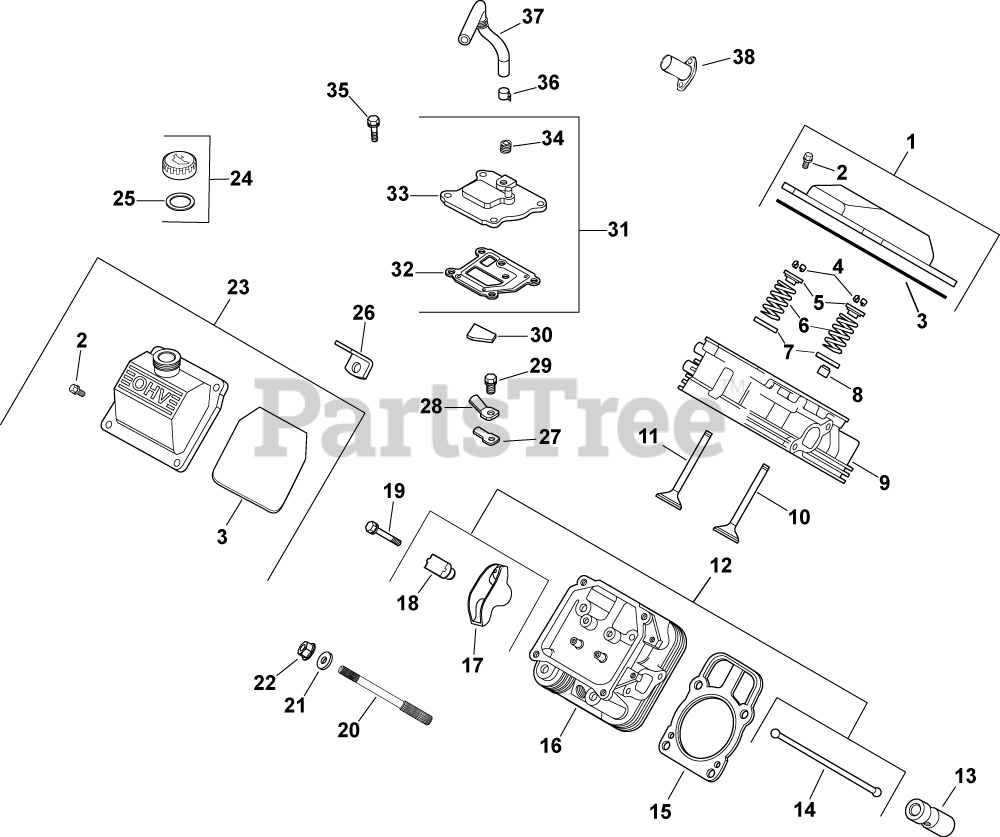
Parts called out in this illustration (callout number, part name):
1	KIT, VALVE COVER-PLAIN
2	SCREW, SHOULDER
4	KIT, RETAINER
5	RETAINER, VALVE SPRING - USE 25 173 28-S
6	SPRING, VALVE
7	RETAINER, SPRING
8	SEAL, VALVE STEM - (#2503214S)
9	HEAD, SERVICE ASSY CYL #1-USE 24 318 106
10	VALVE, INTAKE (STD)
11	VALVE, EXHAUST (STD) - USE 32 016 01-S
12	KIT, VALVE TRAIN
13	LIFTER, HYDRAULIC VALVE-USE 25 351 10-S
14	ROD, PUSH
15	CYL HEAD GASKET KIT-USE 24 841 04-S
16	HEAD, SERVICE ASSY CYL #2-USE 24 318 114
17	ARM, ROCKER
18	PIVOT, CYLINDRICAL ROCKER ARM-USE 24 599
19	SCREW, FLG M6X1.0X34
20	STUD, M8X1.25
21	WASHER, FLAT 8.6 MM
22	NUT, FLG M8X1.25
23	KIT, VALVE COVER-OIL FILL
24	KIT, OIL FILL CAP (YELLOW)
25	O-RING, DIPSTICK
26	STRAP, LIFTING-USE 25 445 03-S
27	REED, BREATHER
28	RETAINER - UE 66 018 04-S
29	SCREW, FLG THD FRM M5X.8X10
30	FILTER, BREATHER-USE 24 050 11-S
31	KIT, BREATHER ASSEMBLY
33	COVER, BREATHER -USE 24 033 01-S
34	PLUG, CTSK PIPE 1/8"
35	SCREW,FLG THD FRM M6X1.0X20-(#25086396S)
36	CLAMP, HOSE 1/2" USE 25 237 14-S
37	HOSE, BREATHER-USE 24 326 89-S
38	LINER, EXHAUST PORT-USE 24 605 07-S
2401602-S	VALVE, EXHAUST (.25)
2401702-S	VALVE, INTAKE (.25)
2535714-S	Lubricant, Camshaft/Lifter (0.25 oz.)
24755147-S	KIT, CYLINDER HEAD HARDWARE
